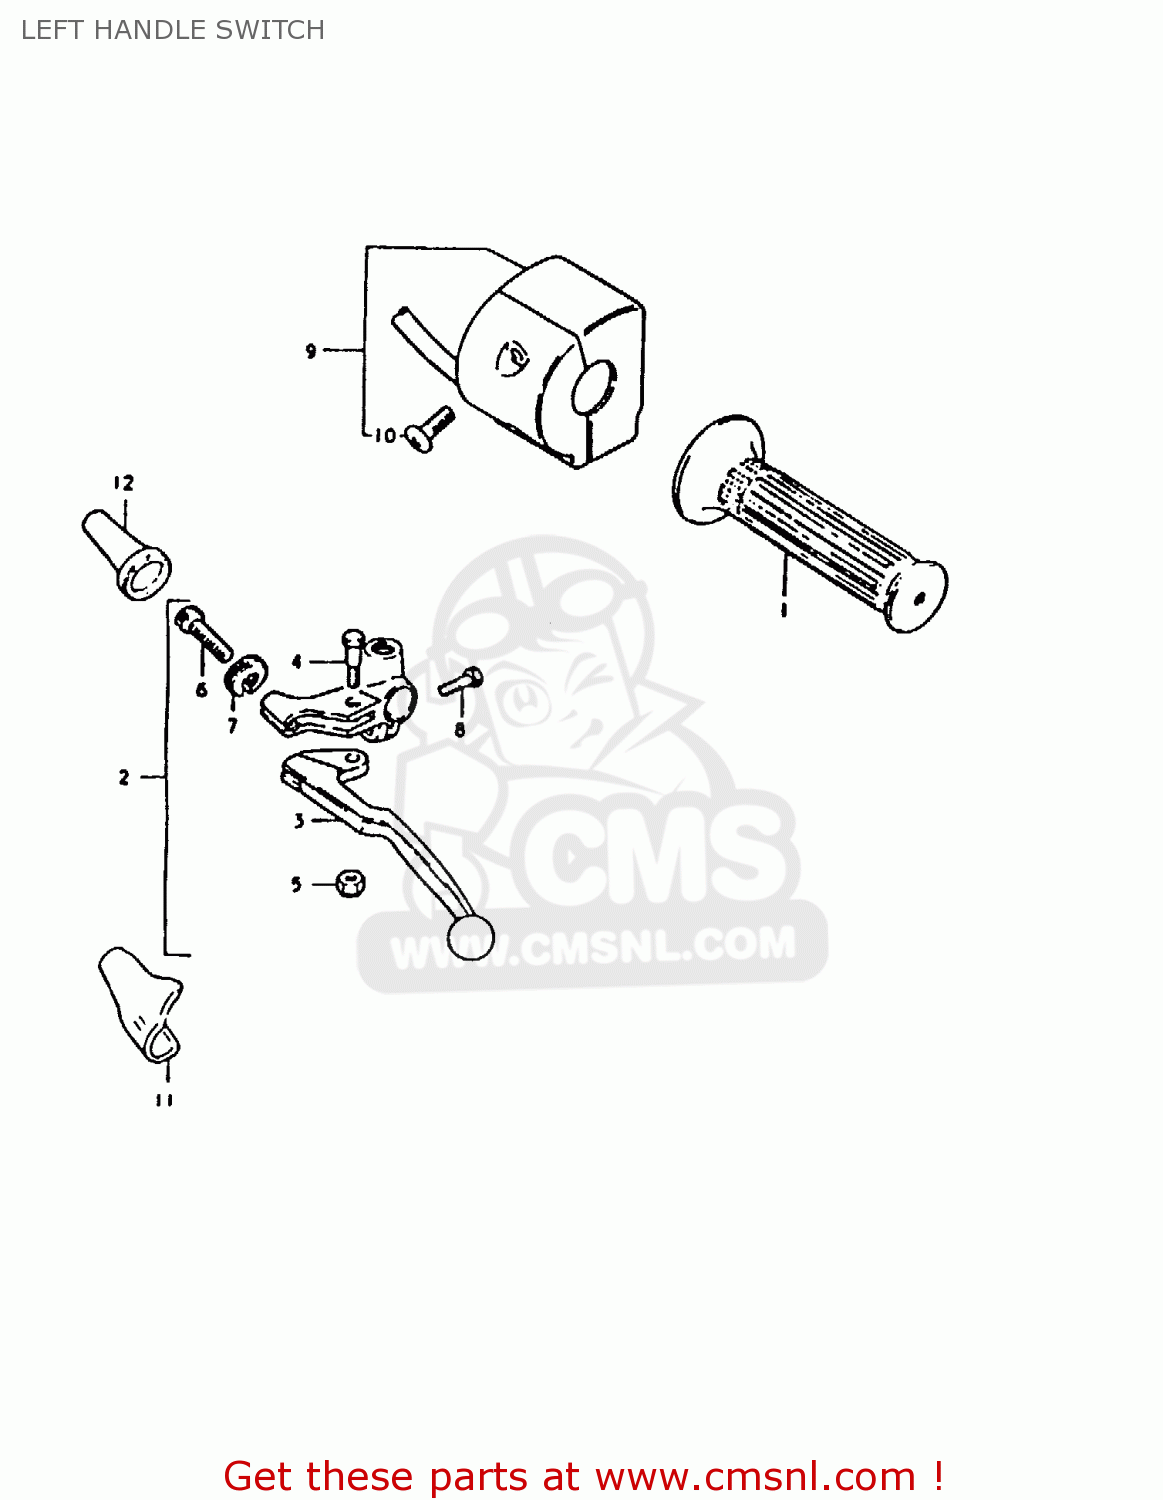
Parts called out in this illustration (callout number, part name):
1	GRIP,LEFT
2	LEVER ASSY, CLUTCH
3	LEVER,CLUTCH
4	BOLT,LEVER
5	NUT 6MM
6	ADJUSTER,CABLE
7	NUT,CABLE ADJUSTER
8	BOLT
9	SWITCH ASSY, HANDLE LH
10	SCREW
11	COVER,CLUTCH LEVER
12	BOOT,CLUTCH CABLE
